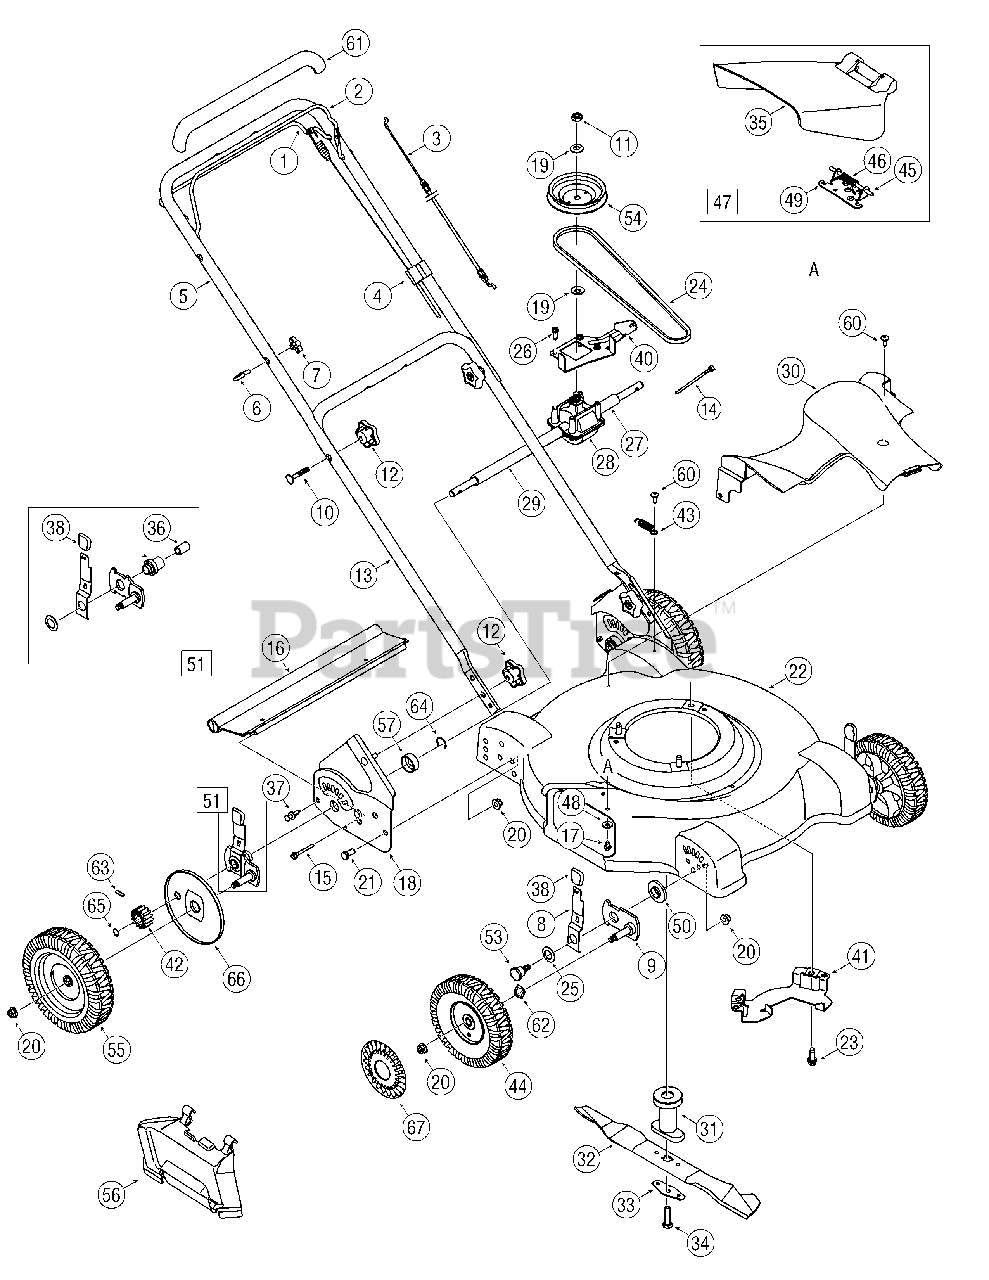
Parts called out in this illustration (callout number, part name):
1	Drive Control
3	Blade Control Cable
4	Drive Control Cable
7	Wing Nut, 1/4-20
8	Spring Lever
9	Pivot Arm Assembly
10	Carriage Bolt, 5/16-18 x 2.0
11	Jam Nut 7/16-20
12	Star Knob
15	Hinge Screw 1/4-20
17	Hex Screw, 1/4-20 x.500
20	Lock Nut, 3/8-16
21	Hex Head Screw 3/8-16 x 1.0
24	V-Belt, 3L x 39.44
26	Hex Head Screw 1/4-20
27	Sleeve Spacer, .550 ID
28	Transmission Assy. Comp.
29	Sleeve Spacer, .550 ID x 8.968
30	Transmission Cover
31	Blade Adapter
32	22" Mulching Blade
33	Bell Blade Support
34	Hex Cap Screw, 3/8-24 x 1.5
35	Side Discharge Chute
36	Slv. Bearing, .502 x.627 x 1.00
37	Plastic Rivet
38	Adjustment Knob
40	Transmission Belt Keeper
41	Transmission Belt Keeper
42	Spur Gear 14T - RH
42	Spur Gear 14T - LH
43	Extension Spring
44	Front Wheel 7 x 2.125
45	Hinge Pin
46	Torsion Spring
47	Side Discharge Assembly
48	Bell Washer, .265 ID x.75
49	Deflector Chute Adapter
50	Height Adjustment Bearing
51	Rear Lever Assembly - LH
51	Rear Lever Assembly - RH
53	Shoulder Screw, 3/8-16
54	Input Pulley
55	Rear Wheel 8 x 2.125
56	Mulching Baffle
57	Bearing Support Spacer
60	Shoulder Screw 1/4-14
61	Snap-on Bail Cover
62	Wave Washer
63	Pin
64	Retainer Ring
67	Hubcap
